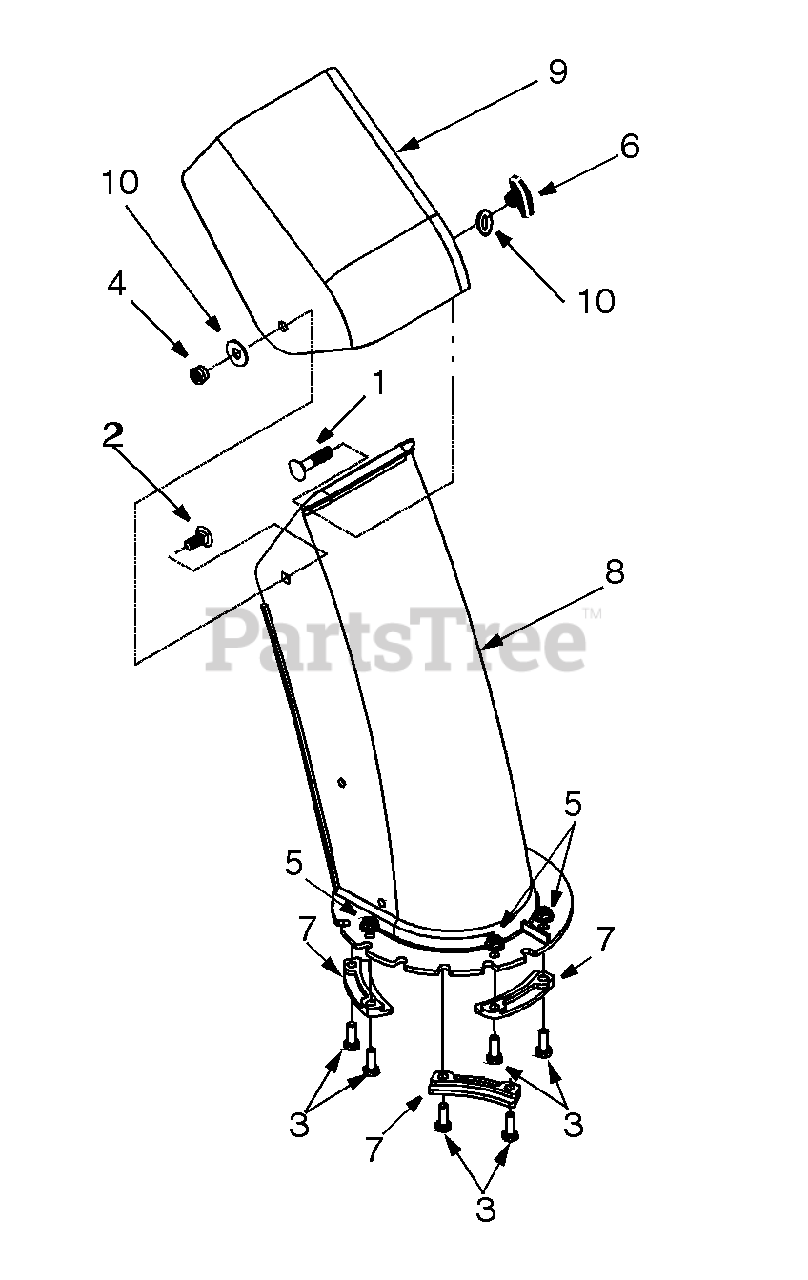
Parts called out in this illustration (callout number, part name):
1	Carriage Screw 5/16-18 x 1.0"
2	Carriage Bolt 5/16-18 x 0.75"
3	Hex Screw 1/4-20 x 0.75"
4	Hex Lock Nut
5	Flanged Lock Nut
7	Chute Flange Keeper
8	Lower Chute
9	Upper Chute
